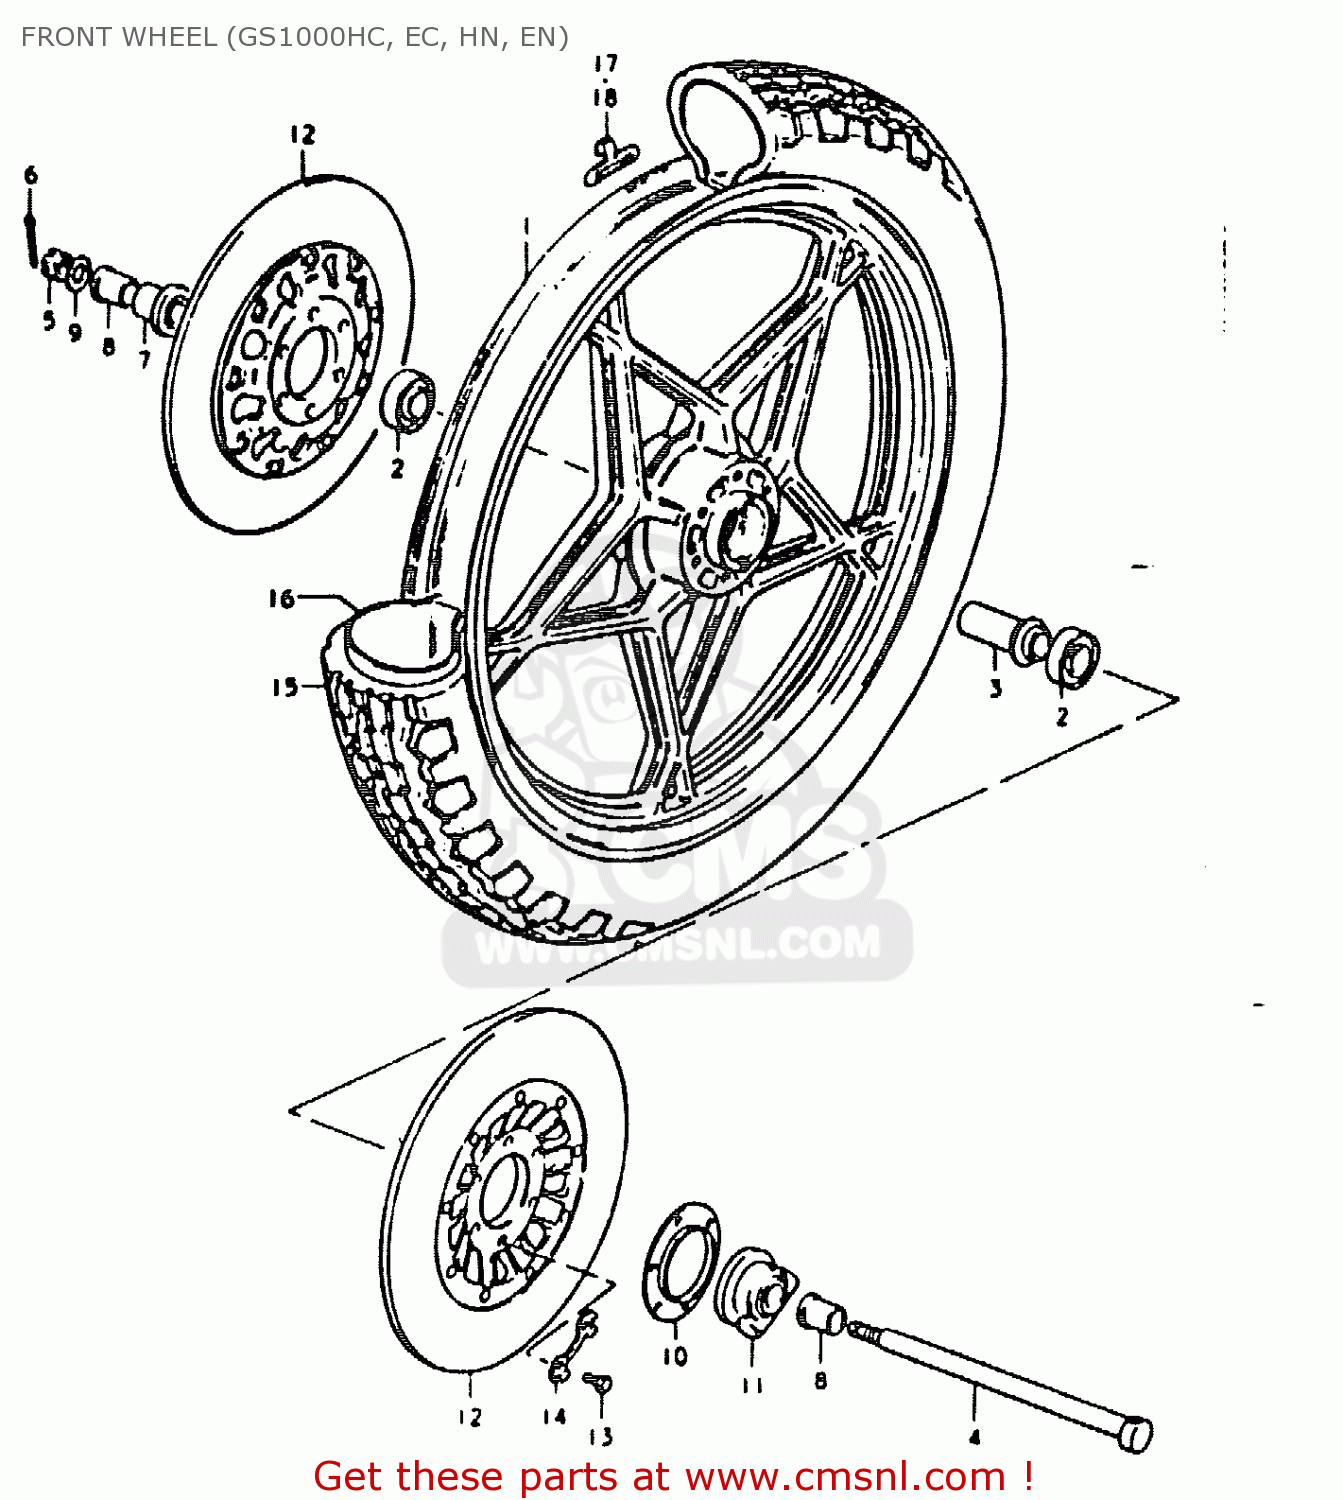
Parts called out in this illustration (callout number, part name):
1	WHEEL, FRONT
2	BEARING
3	SPACER,FR HUB BEARING
4	AXLE,FR
5	NUT 12MM
6	COTTER PIN
7	SPACER,FR AXLE,R
8	SPACER,FR AXLE,L
9	WASHER
10	DUST SEAL
11	BOX ASSEMBLY,SPEEDOMETER GEAR
12	DISC,BRAKE
13	BOLT(8X30)
14	WASHER
15	TIRE,FRONT
16	TUBE,INNER
17	BALANCER,WHEEL
18	BALANCER,WHEEL
